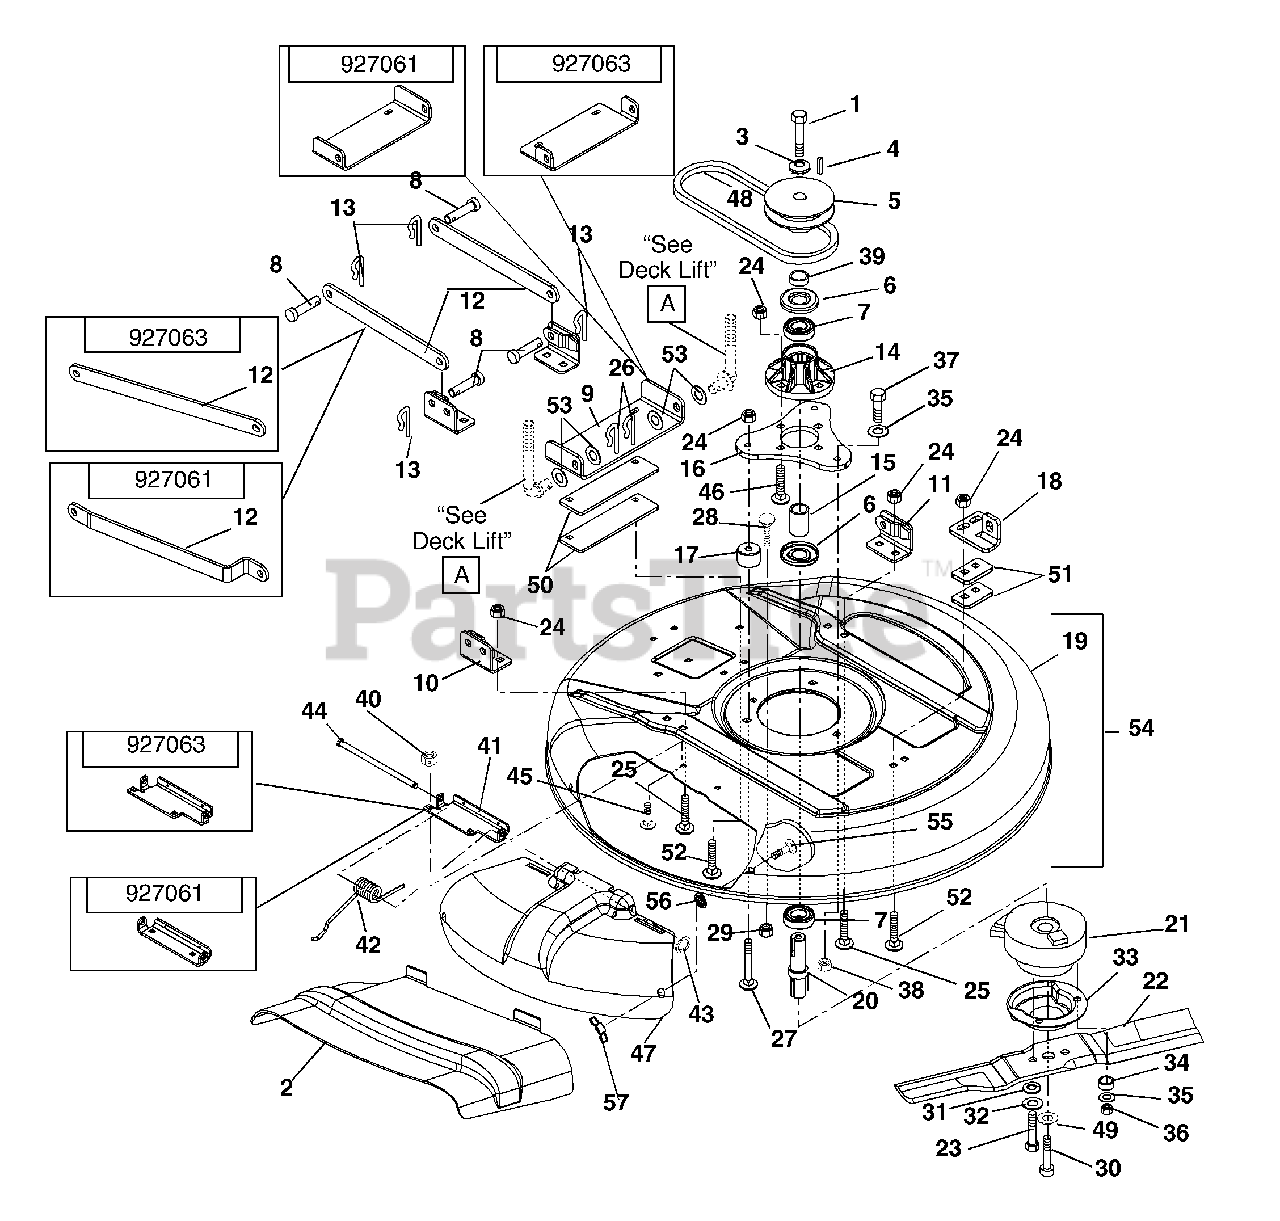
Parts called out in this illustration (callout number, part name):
1	BLT-HEX .38-16X1.00 YZ GR8
2	DISCHARGE CHUTE
3	WASHER, CUPPED SERRATED, .375
4	KEY, SQ .25 X .38 X .25
5	SHEAVE, 4.25 DIA A-SECTION
6	SHEAVE, 4.75 DIA A-SECTION
7	BRG-BALL 1.0X2.0X.56 (1641)
8	PIN-CLEV .494X1.00 BLKZC
9	BRKT, REAR HANGER (28" DECK)
9	BRKT, FRONT LIFT (32" DECK)
10	BRKT, 28" DECK STABILIZER
10	WLDMT-DECK LINK (RH)
11	WLDMT-DECK LINK (RH)
11	WLDMT-DECK LINK (LH)
12	STABILIZER, 28" DECK (RH)
12	LINK STABILIZER 32"
13	CLIP, SPRING
14	ASSY-SPINDLE HSG
15	SPACER, 1.001 X 1.25 X 1.76
16	SPINDLE MOUNT PLATE
17	SPACER-MOUNTING PLATE
18	BRKT, FRONT HANGER (28" DECK)
18	BRKT, FRONT LIFT (32" DECK)
19	DECK, 28" RER
19	DECK, RER/SZ 32"
20	SHAFT, 28" AND 32" INPUT
21	KIT, CLUTCH (1232 RER)
21	KIT, CLUTCH (1028 RER)
22	BLADE-CUTTING 28"
22	BLADE, 32" RER/ZS
23	BLT-HEX M10X1.25X30 CLS 10.9
24	NUT-LK-TOP-FLG .38-16 BLKZC
25	BLT-RDHDSQNK .38-16X.75 G5BZ
26	PIN, HAIR, EXT - #16 YWZC
27	BLT-RDHDSQNK .38-16X2.25 G5BZ
28	@BLT-RDHDSQNK .31-18X1.50 G5YZ
29	@NUT-SPNLK-FLG .312-18 YWZC
30	SCR-SKN .5-20X1.25 BTNHD
31	WSHR-LK M 10MM YZ
32	WSHR-FL-STL .406X1.00X.188 YWZ
33	SHIELD, DEBRIS
34	BSHG, SPCR .752X.877X.50 BRZ
35	@WSHR-FL-STL.38X.875X.083 YWZC
36	@NUT-LK-NYL .38-16 YWZC
37	BLT-HEX .38-16X3.00 GR5 FTH YZ
38	@NUT-SPNLK-FLG .375-16 YWZC
39	SPACER 1.008X1.377X.509 ST
40	NUT-LK-FLG .250-20 PL BLK
41	BRKT, 28" MULCH COVER HINGE
41	BKT, HINGE
42	SPRING, TORSION
43	RG-RTNG-EXT .312X.025
44	PIN, HINGE
45	@BLT-RDHDSQNK .25-20X.75 G5YZ
46	@BLT-RDHDSQNK .38-16X1.25 G5YZ
47	COVER, 28" DECK MULCH
47	MULCH COVER, 32" DECK
48	V-BELT, HA-WRAPPED
48	V-BELT HA, 62.1
49	WASHER, FLT STL .5X1.75X.187
50	PLATE, 32" REAR HANGER SPACER
51	PLATE, 32" FRONT HANGER SPCR
52	@BLT-RDHDSQNK .38-16X1.25 BKZC
53	WSHR-FL-STL .518X2.0X.105 YWZC
54	KIT, 28" DECK SERVICE ASSY
54	KIT, 32" DECK SERVICE ASSY
55	BLT-RDHDSQSHK.31-18X.75 GR2 YW
56	NUT-PUSH .312
57	NUT-NYLK WING .312-18 YWZC
